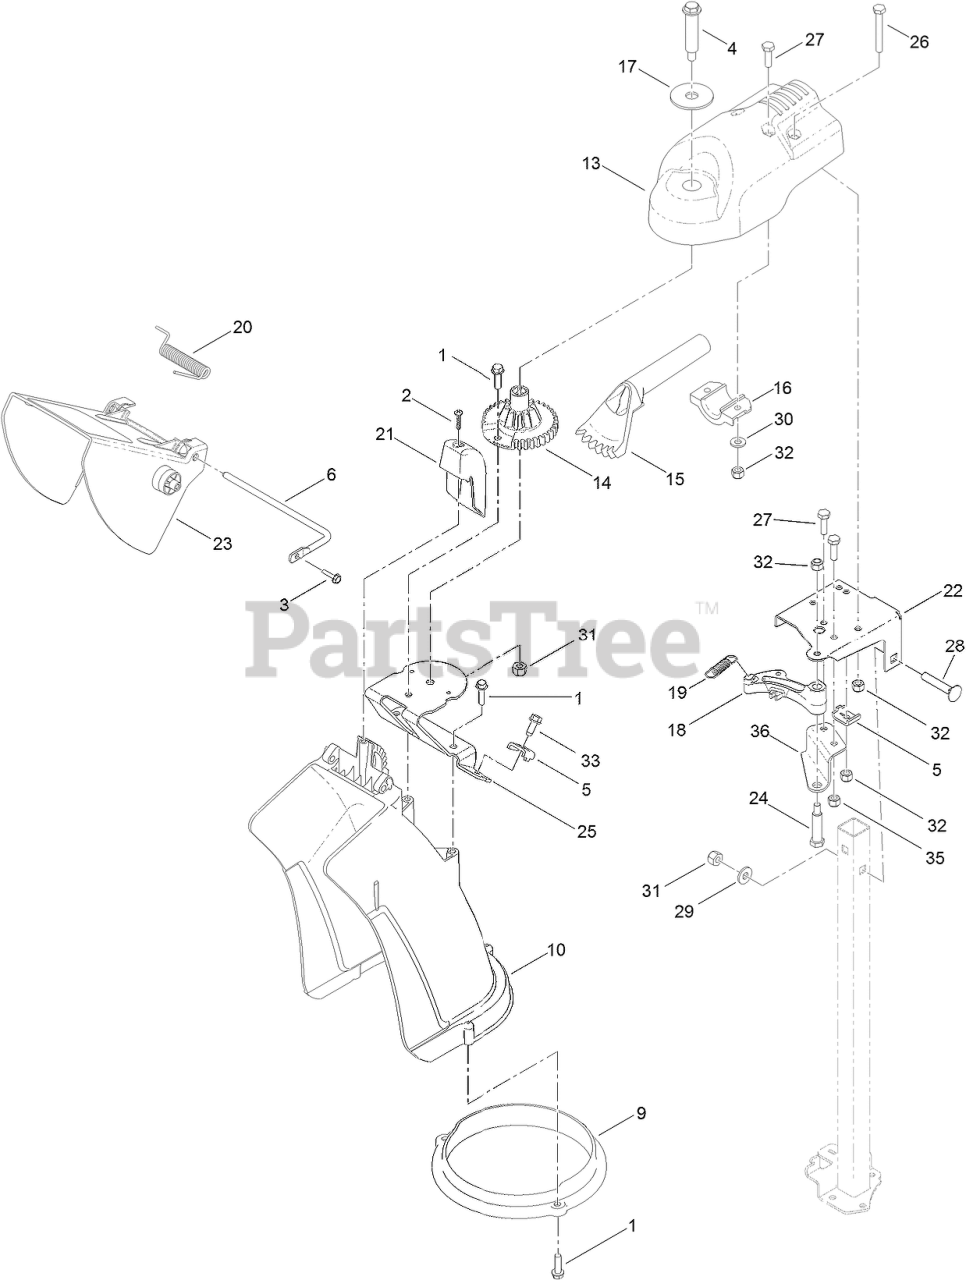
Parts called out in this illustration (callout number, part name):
1	SCREW-HWH
2	SCREW-PPH
3	SCREW-HWH
4	BOLT-SHOULDER
5	CLAMP-CABLE
6	ROD-DEFLECTOR
9	RING-CHUTE
10	CHUTE-DISCHARGE
13	MOUNT-CHUTE, DISCHARGE
14	GEAR-CHUTE
15	GEAR-BEVEL
16	MOUNT-GEAR, BEVEL
17	WASHER-FLAT
18	LATCH-CHUTE
19	SPRING-LATCH, CHUTE
20	SPRING-TORSION
21	CHUTE-COVER
22	BRACKET-SUPPORT, CHUTE
23	DEFLECTOR-CHUTE
24	BOLT-SHOULDER
25	BRACKET-MOUNT, CHUTE
26	SCREW-HH
27	SCREW-HH
28	SCREW-CARR
29	WASHER-FLAT
30	WASHER-FLAT
31	NUT-LOCK, NI
32	NUT-LOCK, NI
33	SCREW-HWH
35	NUT-LOCK, NI
36	BRACKET-SUPPORT, LATCH
